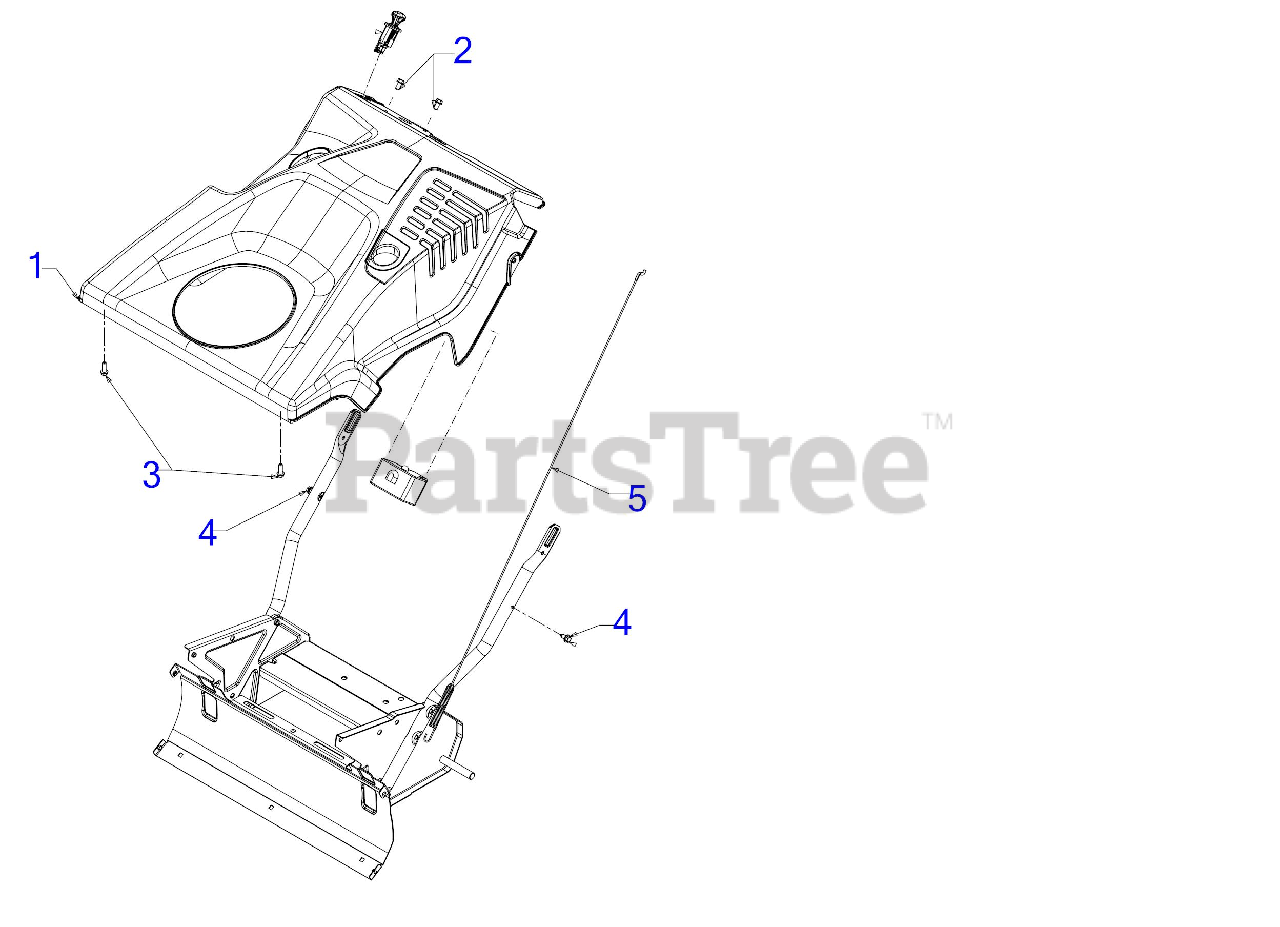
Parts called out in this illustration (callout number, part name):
1	COVER ASSEMBLY
2	HEX SCREW 1/4-15 x .50
3	SCREW 1/4-15 x .750
4	SCREW 1/4-20X.625
5	CLUTCH CABLE 35.03"
